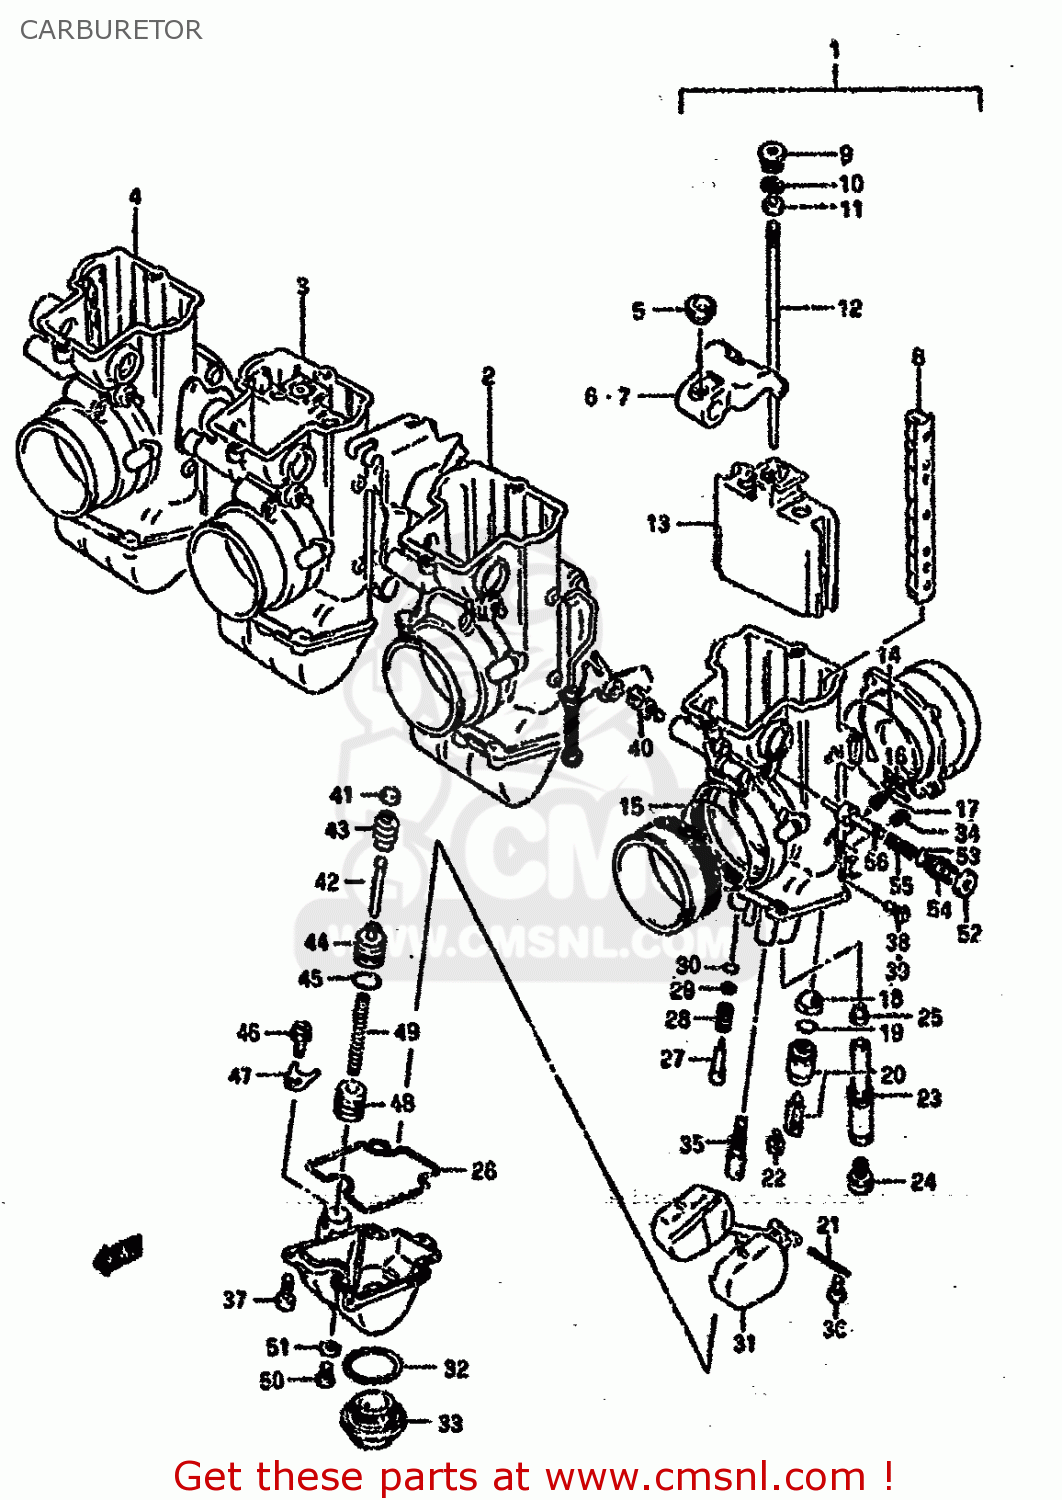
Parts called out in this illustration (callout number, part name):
1	CARBURETOR ASSY,LH
2	CARBURETOR ASSY,ML
3	CARBURETOR ASSY,MR
4	CARBURETOR ASSY,RH
5	RING
6	LEVER ASSY
7	LEVER ASSY
8	BEARING
9	HOLDER
10	E RING,MULTIPLE JET NOZZLE
11	RING
12	NEEDLE,JET (9D1-52-4)
13	VALVE,PISTON (1.0)
14	O RING
15	O RING
16	O RING
17	JET,AIR (70)
18	FILTER
19	O-RING,NEEDLE VALVE
20	VALVE ASSY,NEEDLE (2.8)
21	PIN,FLOAT
22	SCREW
23	HOLDER,JET
24	JET,MAIN(110)
25	JET,NEEDLE (P-4)
26	GASKET
27	SCREW,PILOT
28	SPRING
29	WASHER
30	O RING,PILOT AIR SCREW
31	FLOAT ASSY
32	O RING,DRAIN PLUG
33	BOLT,DRAIN
34	JET,PILOT AIR(120)
35	JET,PILOT(20)
36	SCREW
37	SCREW
38	SCREW
39	SCREW
40	SCREW
41	CAP
42	ROD
43	CAP
44	RING
45	O RING
46	SCREW
47	PLATE
48	PLUNGER
49	SPRING
50	SCREW
51	WASHER
52	CAP,STARTER VALVE
53	O RING
54	HOLDER,GUIDE
55	SPRING
56	PLUNGER
